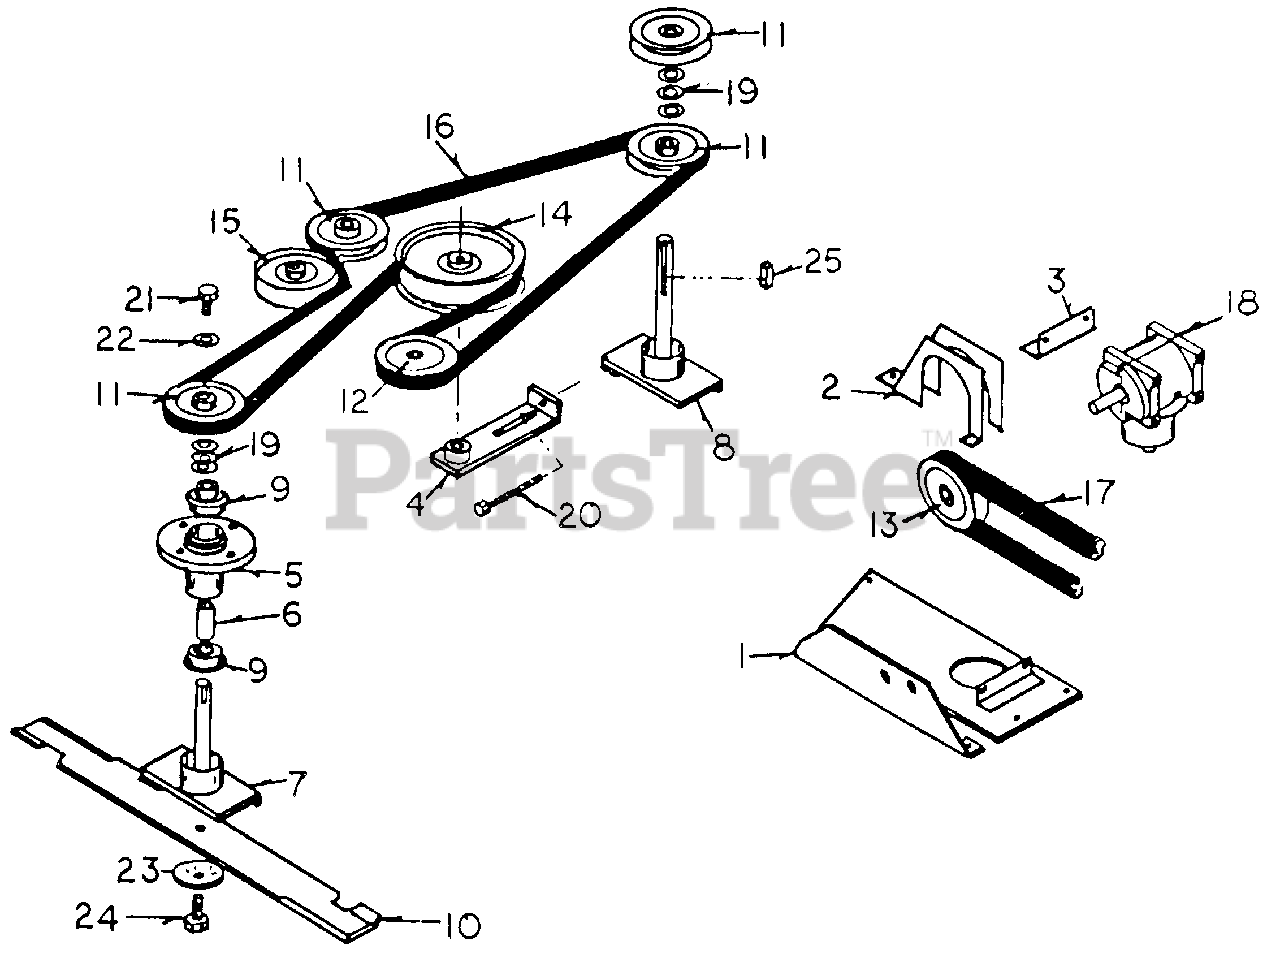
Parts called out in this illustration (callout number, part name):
2	Belt Guard
3	Gearbox Mount Angle
4	Belt Tightener
5	Spindle Housing
6	Spindle Spacer
7	Spindle Shaft
8	Spindle Shaft, Bong
9	Spindle Bearing
10	B1ade
11	Spindle Pulley
12	Gearbox Pulley, Out Put
13	Gearbox Pulley, In Put
14	Idler Pulley, Large
15	Idler Pulley, Small
17	Deck Drive Belt
20	Adjustment Bolt
21	Hex Bolt, S/16-24 x 3/4"
22	Washer, 5/16", 10 Ga.
24	Hex Bolt, 3/8-24 x 1-1/4"
25	Key Stock, 3/16"
